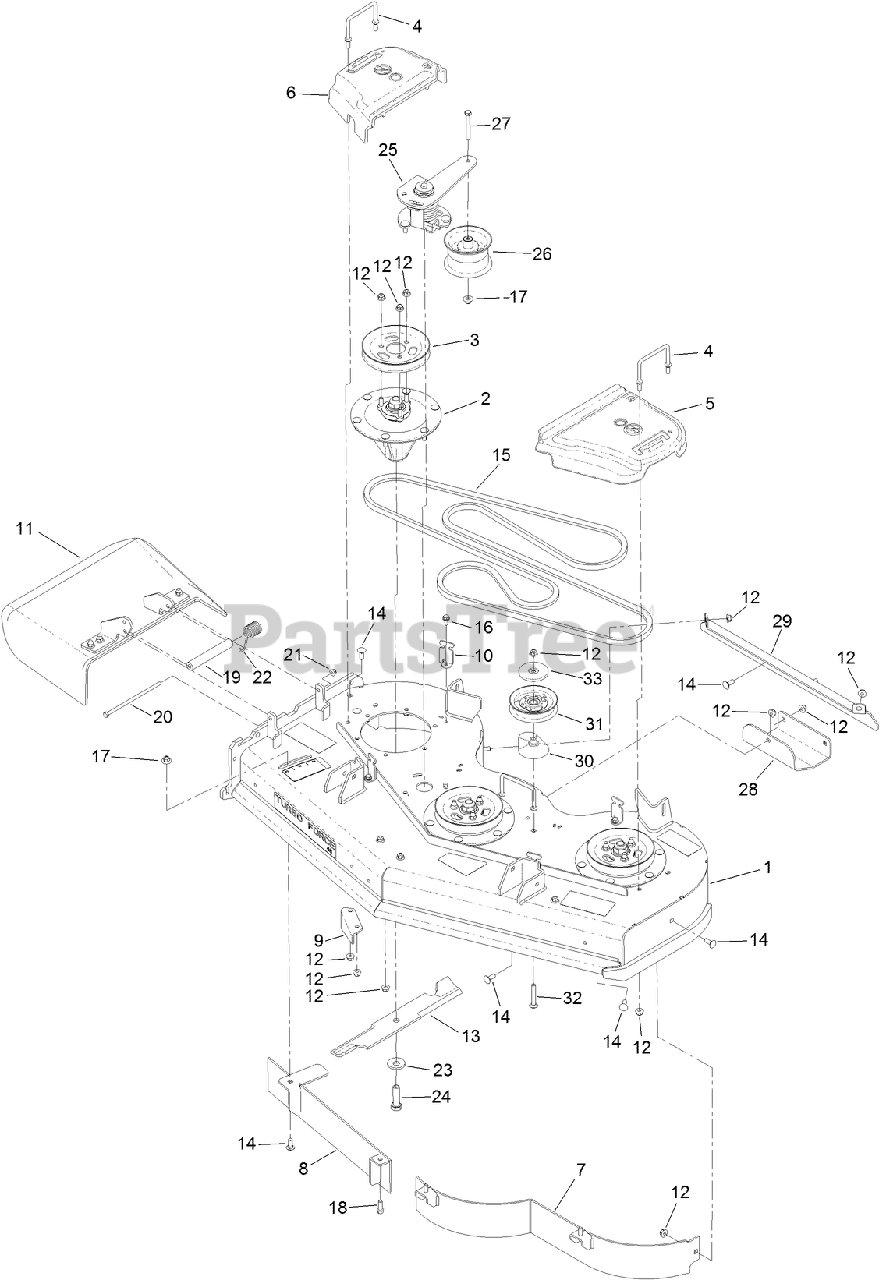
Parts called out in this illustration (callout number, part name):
1	DECK ASM
2	SPINDLE ASM
3	PULLEY
4	WIREFORM-COVER
5	COVER-BELT, LH
6	COVER-BELT, RH
7	48 INCH BAFFLE ASM
9	BAFFLE-DISCHARGE
10	BRACKET-COVER
11	DEFLECTOR ASM
12	NUT-HF, NI
13	BLADE-16.5 INCH (HIGH FLOW)
14	BOLT-CARR
15	BELT-V
16	SCREW-HWHTF
17	NUT-FLANGE, NI
18	SCREW-HWH
19	SPACER
20	SCREW-HH
21	NUT-HF, NI
22	SPRING-TORSION
23	Washer-Blade Bolt, Heavy
24	SCREW-BLADE
25	TORSION IDLER ASM
26	PULLEY-IDLER
27	SCREW-HH
29	BRACKET-SKID
30	SPACER-PULLEY
31	IDLER-PULLEY, FLAT
32	SCREW-CARR
33	SHIELD-DUST
